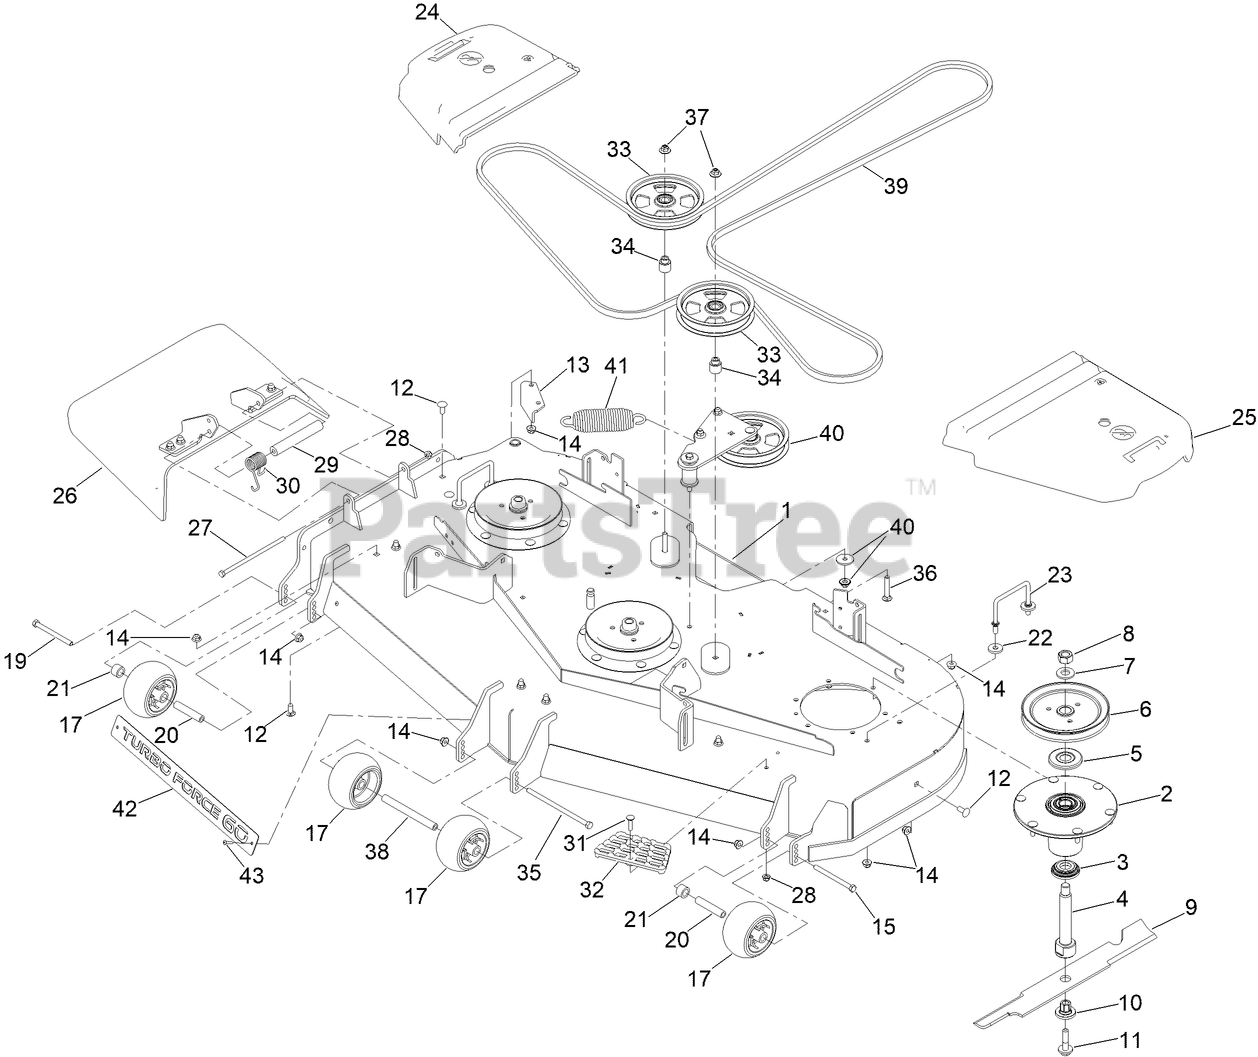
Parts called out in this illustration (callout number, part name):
1	DECK DECAL ASM
2	SPINDLE ASM
3	GUARD-BOTTOM
4	SHAFT-SPINDLE
5	GUARD-BEARING, TOP
6	SHEAVE-DRIVE, BLADE
7	WASHER
8	NUT-HEX
10	BUSHING-HEX
11	SCREW-SEMS
12	SCREW-CARR
13	BAFFLE-DISCHARGE
14	NUT-HF, NI
15	SCREW-HH
17	ROLLER-SCALP, ANTI
19	SCREW-HH
20	TUBE-SHAFTING
21	TUBE-SPACER
22	WASHER
23	WIREFORM-COVER
24	COVER-BELT, RH
25	COVER-BELT, LH
26	RUBBER DEFLECTOR ASM
27	SCREW-HH
28	NUT-HF, NI
29	SPACER
30	SPRING-TORSION
31	SCREW-CARR
32	STEP-DECK
33	PULLEY-IDLER, FLAT
34	BUSHING, IDLER
35	SCREW-HH
36	SCREW-CARR
37	NUT-FLANGE, NI
38	SPACER-WHEEL
39	BELT-V
40	IDLER ARM ASM
41	SPRING-EXTENSION
42	PLATE-TURBO FORCE [BLACK]
43	RIVET-TRIFOLD
